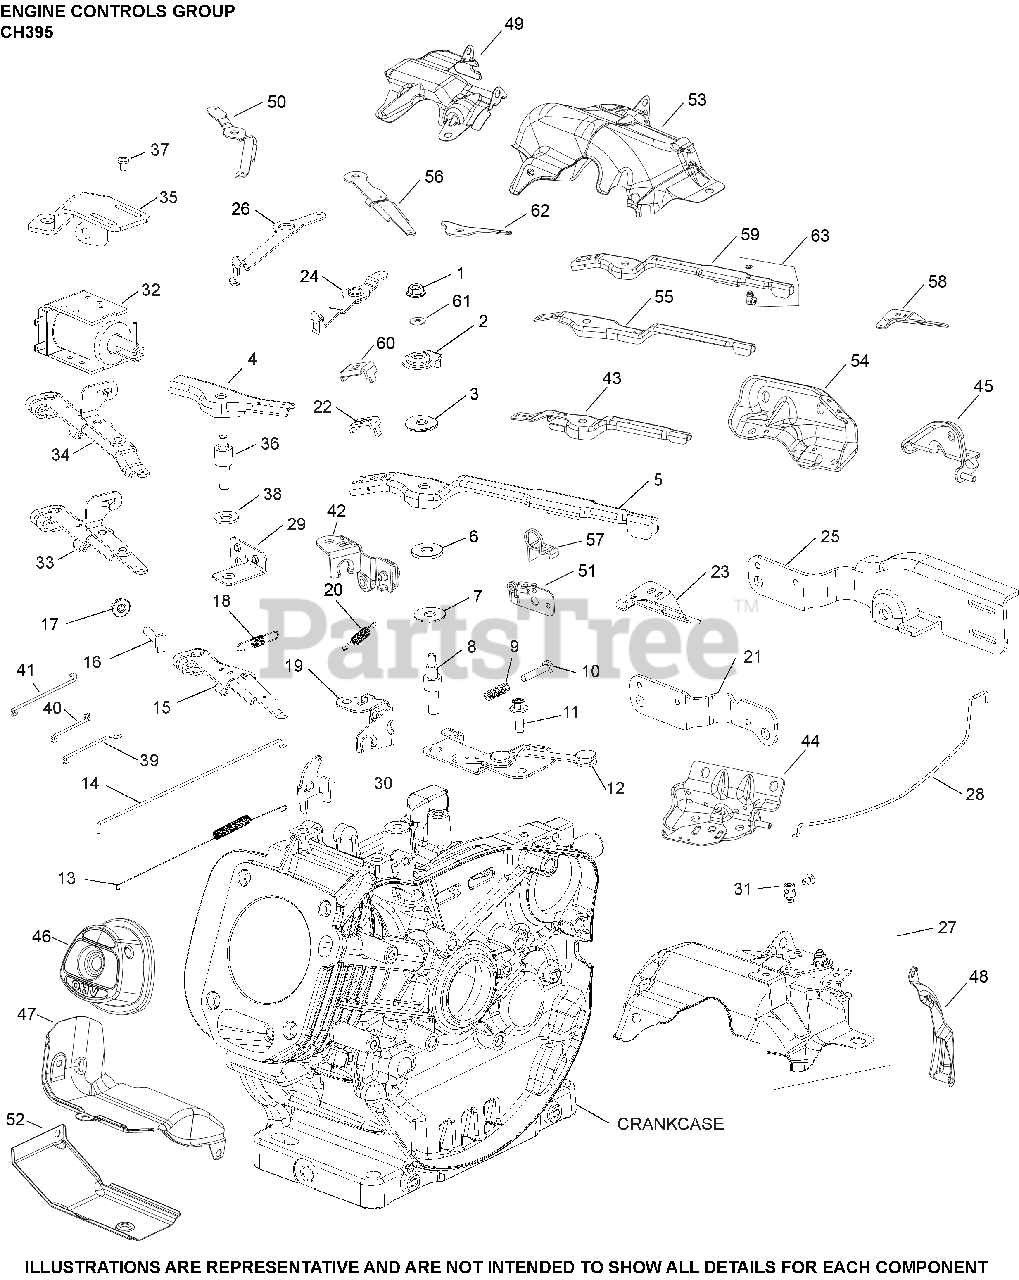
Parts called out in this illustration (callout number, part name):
1	NUT, HEX FLANGE LOCK (M6)
2	WASHER, CONTROL LEVER
3	WASHER, SPRING
5	CONTROL LEVER ASSEMBLY
6	WASHER, NYLON CONTROL LEVER
7	WASHER, FLAT
8	STUD, CONTROL LEVER
9	SPRING, COMPRESSION
10	SCREW, SPEED ADJUSTING
12	BRACKET, CONTROLS ASSY
13	SPRING, LINKAGE
14	LINKAGE, GOVERNOR
15	KIT, GOVERNOR LEVER
16	SCREW, RECTANGLE HEAD (M6)
17	NUT, HEX FLANGE (M6) - USE 14 100 16-S
18	SPRING, GOVERNOR
20	SPRING, THROTTLE RETURN
22	CLAMP, CABLE
23	BRACKET, BOWDEN CABLE ASSY
31	KIT, CABLE CLAMP
